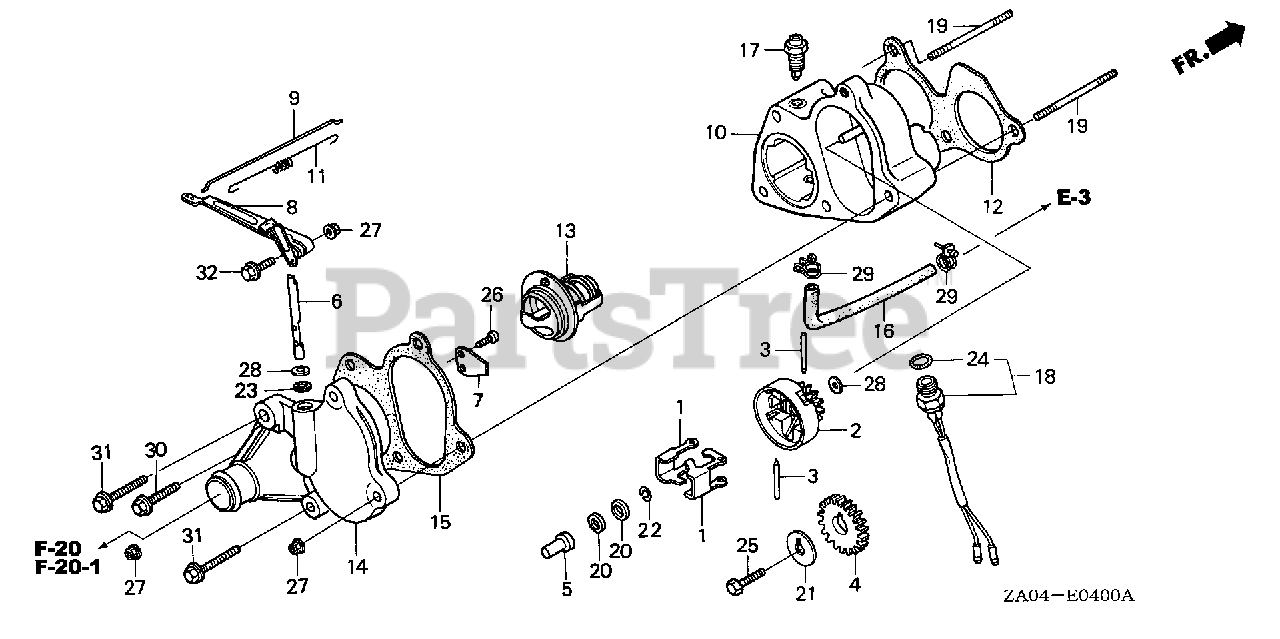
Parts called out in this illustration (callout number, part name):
1	WEIGHT, GOVERNOR
2	HOLDER, GOVERNOR WEIGHT
3	PIN, GOVERNOR WEIGHT
4	GEAR, GOVERNOR DRIVE
5	SLIDER, GOVERNOR
6	SHAFT, GOVERNOR ARM
7	FORK, GOVERNOR
8	ARM, GOVERNOR (NOT AVAILABLE)
9	ROD, GOVERNOR ARM (NOT AVAILABLE)
10	CASE, GOVERNOR (NOT AVAILABLE)
11	SPRING, THROTTLE RETURN
12	GASKET, GOVERNOR CASE
13	THERMOSTAT ASSY.
14	COVER, THERMOSTAT (NOT AVAILABLE)
15	GASKET, THERMOSTAT COVER
15	GASKET, THERMOSTAT COVER (NOT AVAILABLE)
16	HOSE, WATER BYPASS
17	BOLT, BREATHING WATER
19	BOLT, STUD (6X75)
20	WASHER, THRUST (6MM)
21	WASHER, PLAIN (6MM)
22	CLIP, GOVERNOR HOLDER
23	OIL SEAL (6X11X4) (ARAI)
25	BOLT, HEX. (6X22)
26	SCREW, PAN (3X6)
27	NUT, FLANGE (6MM)
28	WASHER, PLAIN (6MM)
29	CLIP, TUBE (A13)
30	BOLT, FLANGE (6X28)
31	BOLT, FLANGE (6X60)
32	BOLT, FLANGE (6X22)
